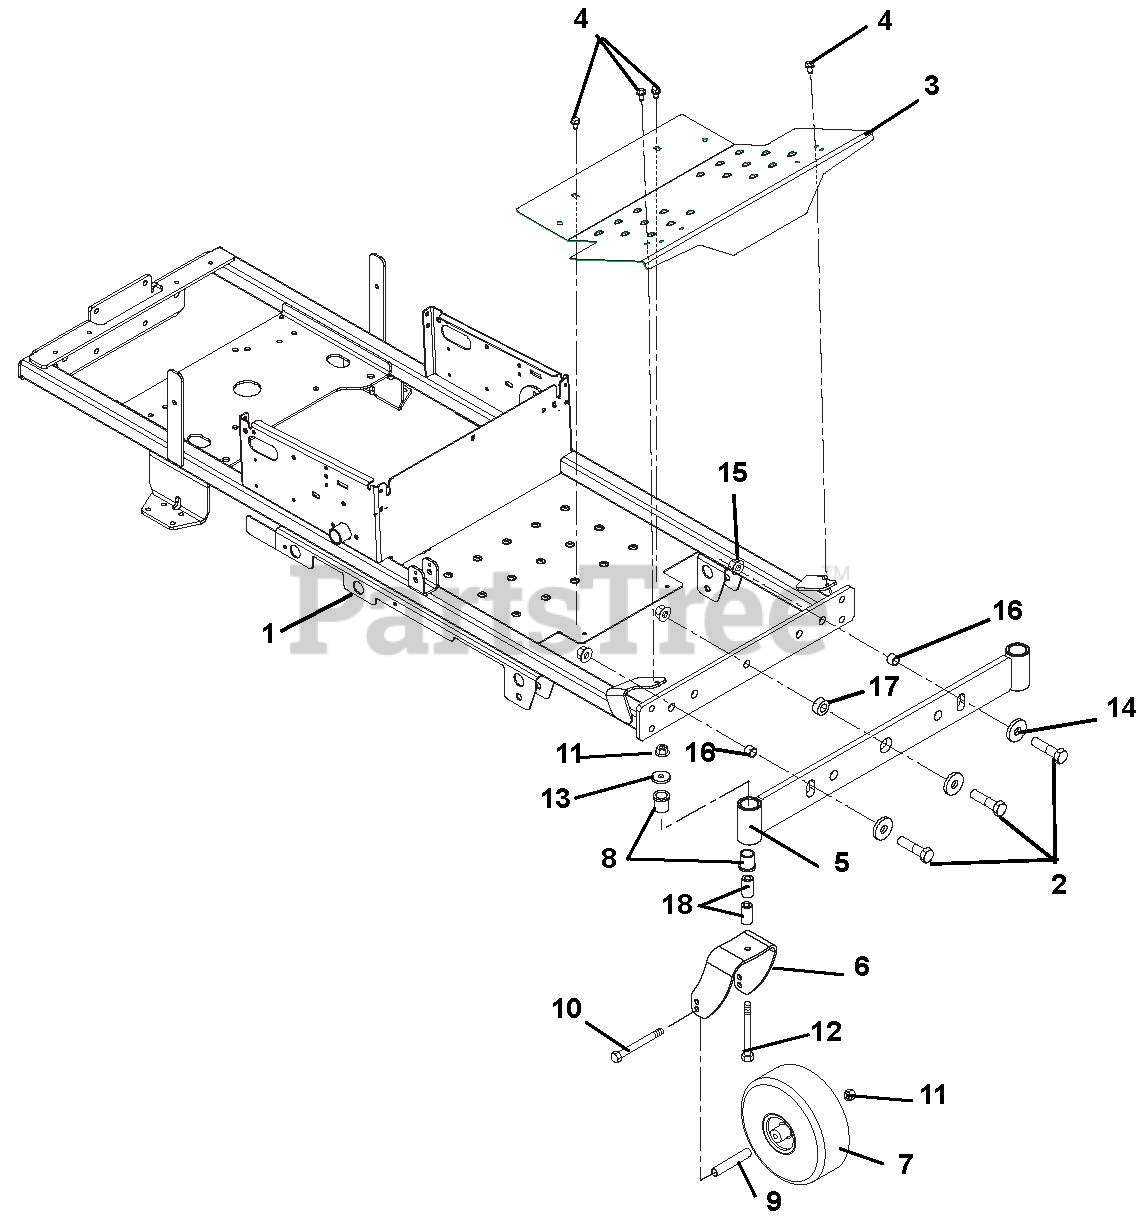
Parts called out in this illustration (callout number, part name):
1	WMT, ZOOM FRAME
2	BLT-HEX .62-11X2.25 YWZC GR8
3	FOOTREST, MZ/ZOOM
4	@SCR-TAP .31-18X.50 HWH TR YWZ
5	WELDMENT, FRONT AXLE
6	FORK, CASTER- WELDED
7	TIRE/WHEEL ASSY, 11X4-5
8	BSHG-FLG 1.00X1.25X1.50X1.50EP
9	SPACER, ROLLED WHEEL
10	@BLT-HEX .50-13X6.50 GR5 YWZC
11	@NUT-LK-NYL-FLG .50-13 YWZC
12	@BLT-HEX .50-13X5.00 GR5 YWZC
13	WSHR-FL-STL.511X1.441X.125 YWZ
14	WSHR-FLT .640X1.75X.250 YWZC
15	@NUT-LK-NYL-FLG .63-11 YWZC
16	SPACER, .750 D X .558 LONG
17	BUSHING, AXLE PIVOT
18	SPACER, CASTER .50X1.00X1.84
